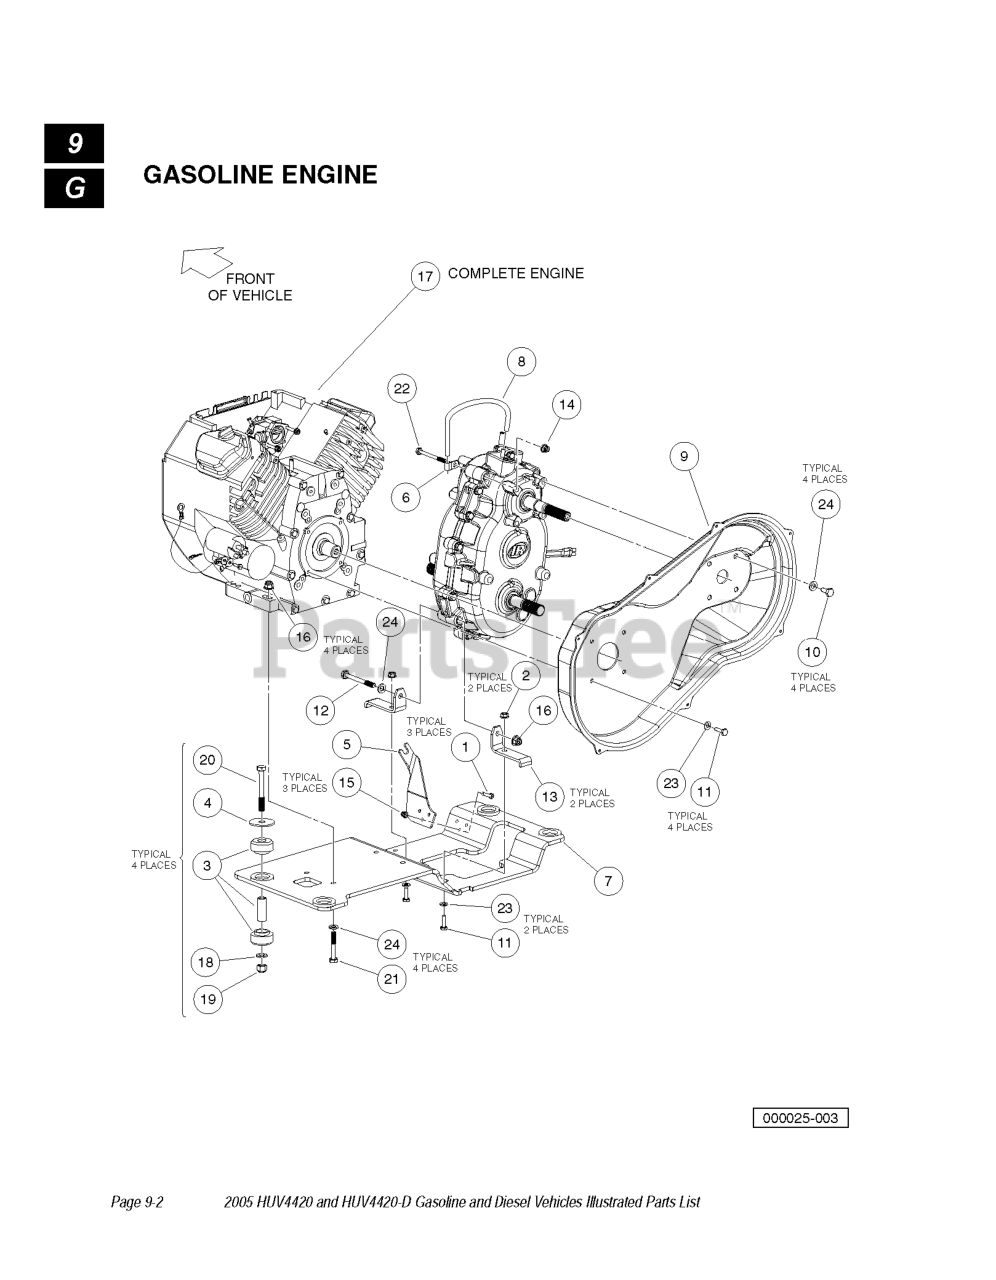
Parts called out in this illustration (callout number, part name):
2	NUT FLG, M8 X 1.25 MECH DEF
3	ISOLATOR, RING AND BUSHING
4	WASHER, SNUBBING, RING N BUSH
5	BRACKET, FNR TRANS CABLE
6	P-CLAMP, INSULATED .312 IN
7	PLATE, ENG MTG, WELD, HONDA
8	HOSE, VENT, TRANSMISSION
9	COVER, CVT INNER, HONDA
10	BOLT, M10 X 1.5 X 20 LOCTITE
11	BOLT, M8 X 1.25 X 25 LOCTITE
12	BOLT, M10 X 1.5 X 100 LOCTITE
13	BRACKET, TRANSMISSION MTG
14	LOCK NUT, FLG M8 X 1.25 NYLON
15	NUT FLG, M6 X 1.0 NYLON
16	NUT FLG M10 X 1.5 NYLON
17	ENGINE, HONDA, NO ACR
18	WASHER, M12 HARD
20	BOLT, M12 X 1.75 X 90
21	BOLT, M10 X 1.5 X 60
22	BOLT, M8 X 1.25 X 80
23	WASHER, M8 HARD
24	WASHER, M10 HARD
